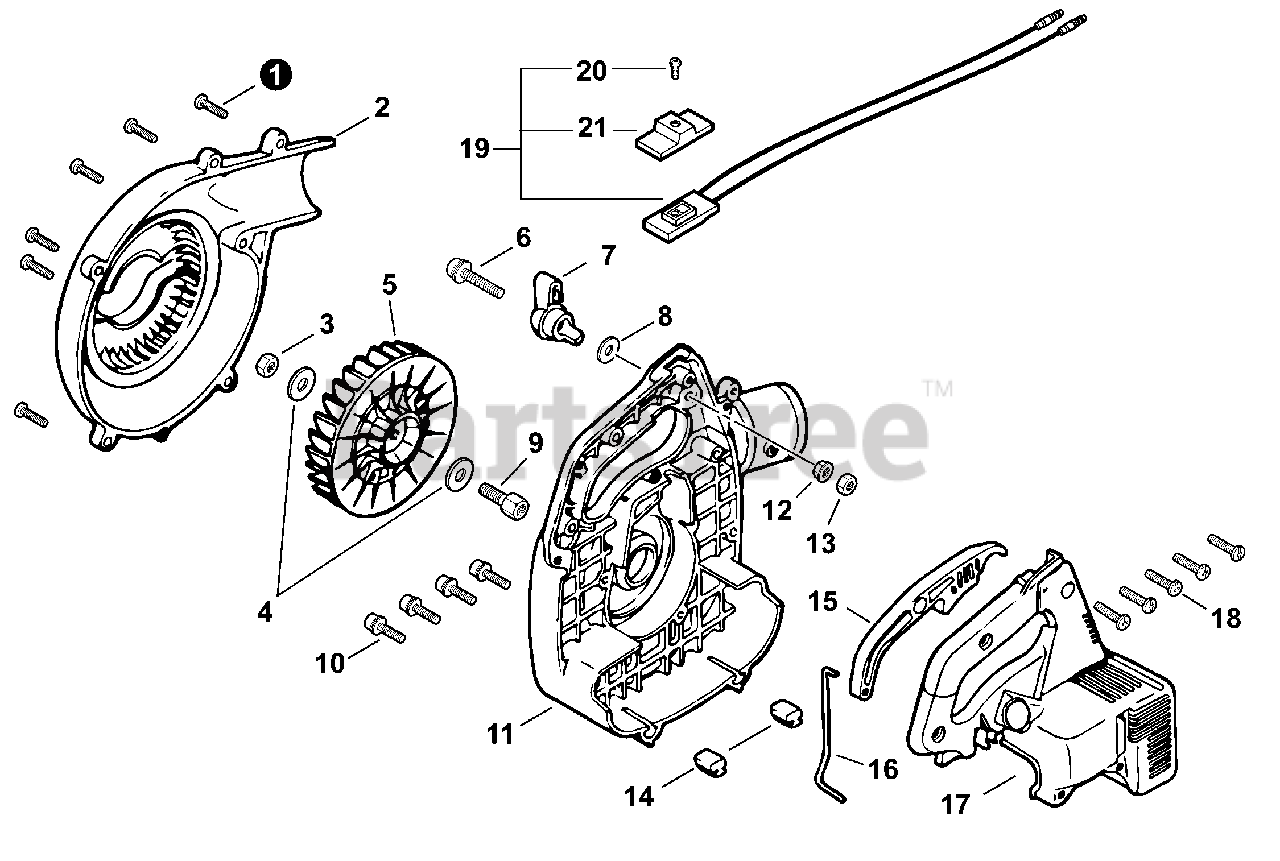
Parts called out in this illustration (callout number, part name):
1	SCREW, TAPPING 5×20
2	COVER, FAN
6	SCREW 5×25
7	LEVER, CRUISE CONTROL
8	WASHER 5.5×12×0.8
9	HUB, FAN
10	SCREW 4×22
11	CASE, FAN
12	NUT, FLANGE M5
15	TRIGGER, THROTTLE
16	ROD, THROTTLE
17	COVER, ENGINE
18	SCREW, TAPPING 5×20
19	SWITCH, ON-OFF
20	SCREW 3×10
21	KNOB, SWITCH
